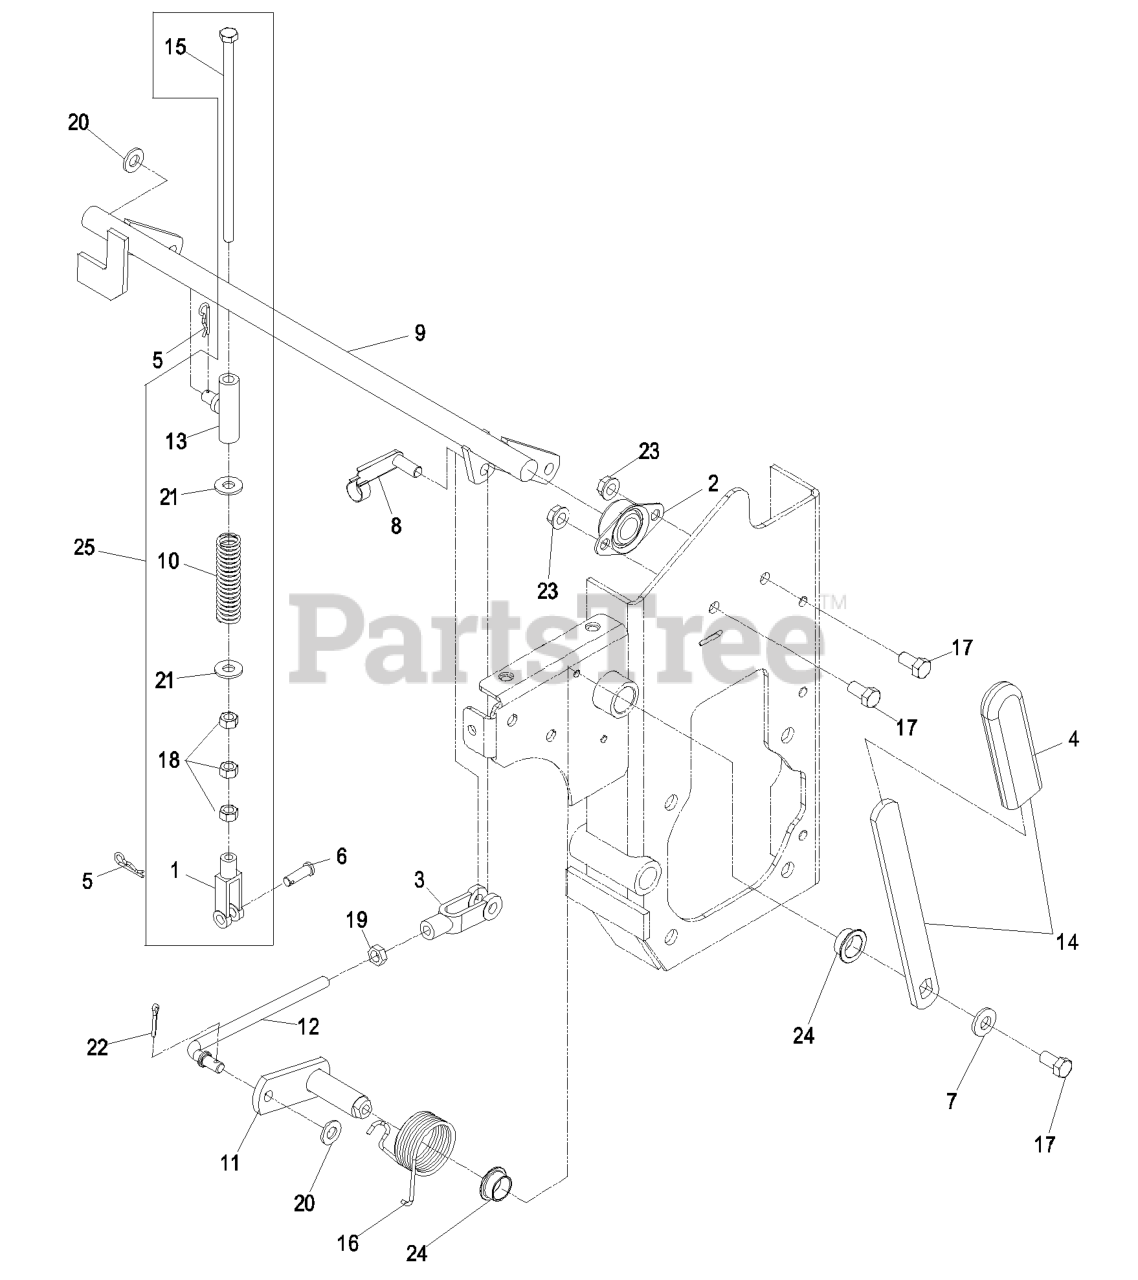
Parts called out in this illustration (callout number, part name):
1	YOKE-ADJUSTABLE
2	BEARING-FLANGE, SIDE
3	YOKE-LINKAGE, BRAKE
4	GRIP-LEVER
5	PIN-COTTER
6	PIN-CLEVIS
7	WASHER-BELLEVILLE
8	PIN-SPRING, CLEVIS
9	WLD, BRAKESHAFT
10	SPRING,COMPRESSION
11	WLD,BRAKE PIVOT (PLATED)
12	ROD,LINKAGE BRAKE (PLATED
13	WLD,SWIVEL BRAKE (PLATED)
14	PARK BRAKE HANDLE ASM
15	SCREW-HH
16	SPRING,TORSION RH
17	SCREW-HH
18	NUT-HEX
19	NUT-HEX
20	WASHER-FLAT
21	WASHER-FLAT
22	PIN-COTTER
23	NUT-HHF, WHIZ
24	BUSHING-BRONZE
25	ASM,BRAKE LINKAGE
